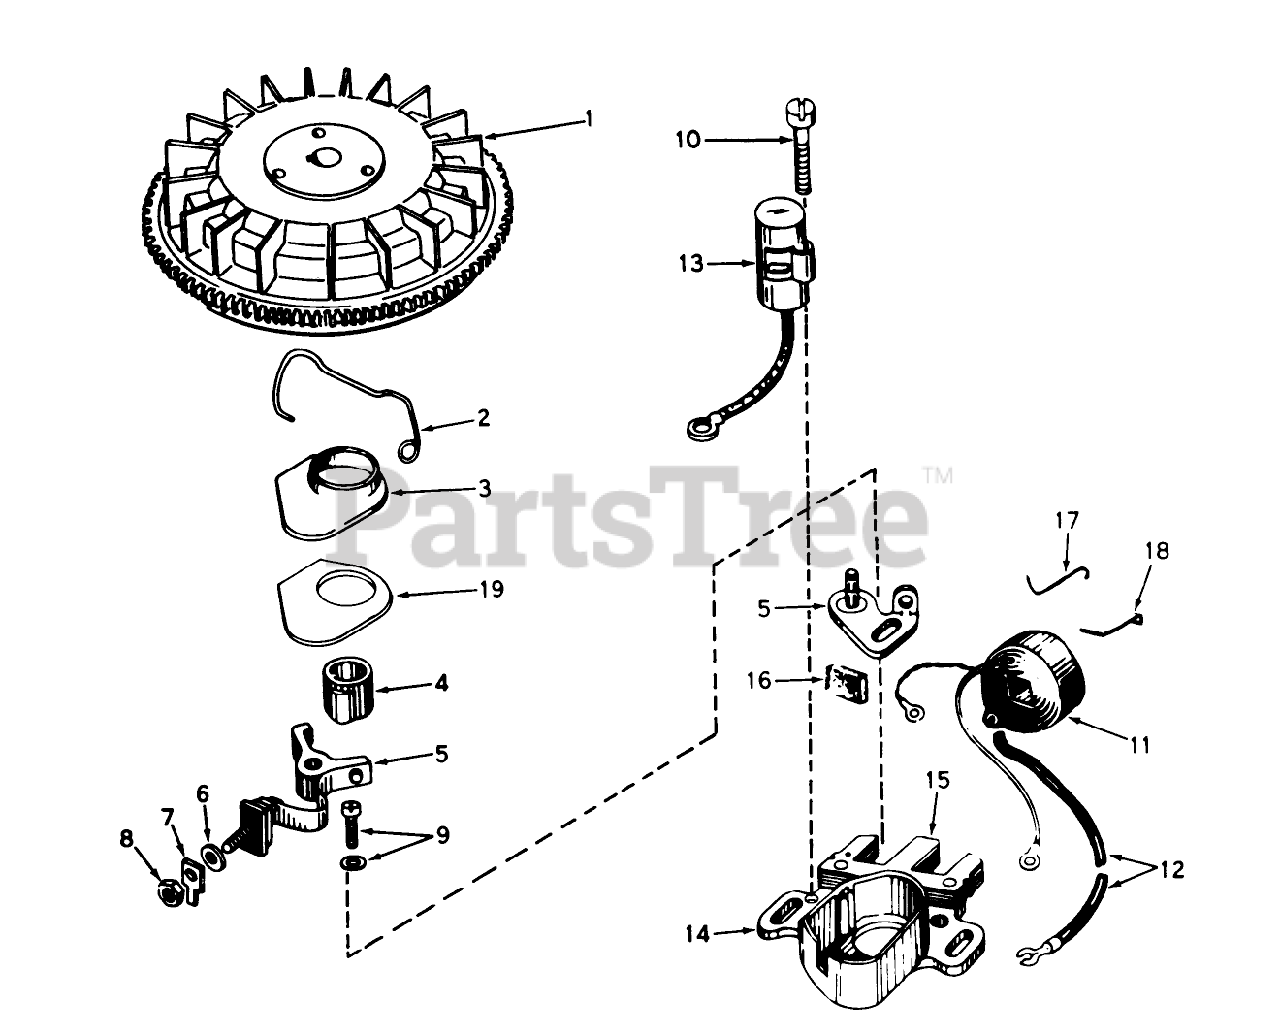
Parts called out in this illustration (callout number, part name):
1	FIywheel
2	Spring Breaker Box
3	Cover, Dust
4	Cam-Breaker
5	Breaker Assy.
6	Washer
7	Terminal
8	DECAL
9	Breaker Screw
10	Condenser Screw
11	Coil Assy. (Incl. No. 12)
12	Wire, Lead
13	Condenser
14	Core Plate
15	Stator Assy., (Incl. Nos. 2, 3, 5 thru 14 16 thru 19)
16	Felt,Cam Wiper
17	Clip, Coil
18	Spring Coil Wedge
19	Gasket Dust Cover
